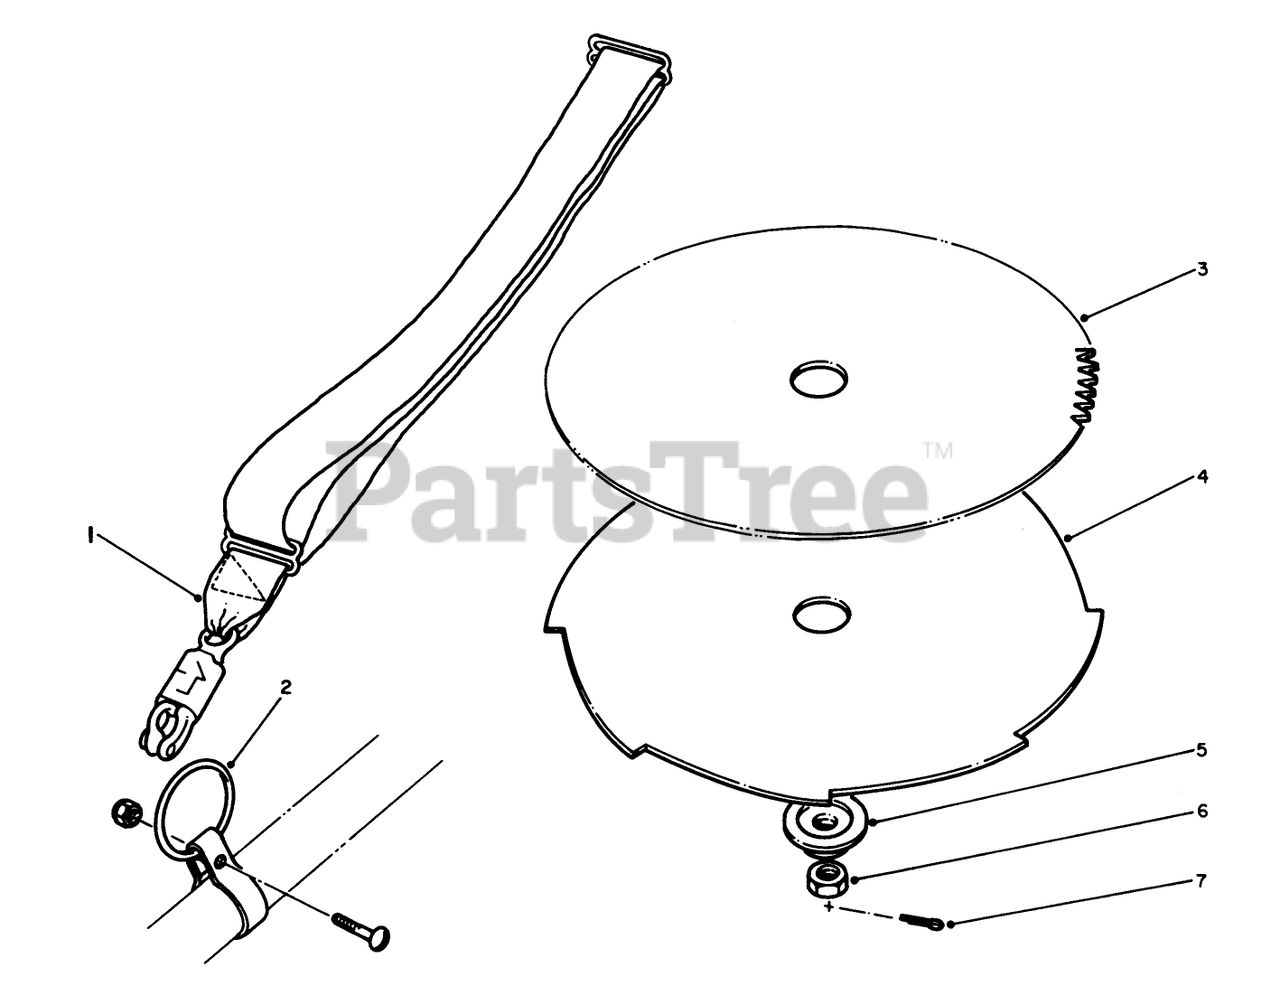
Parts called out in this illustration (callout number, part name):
2	HARNESS CLAMP/RING KIT
3	SAW BLD PKG(8", 80T)
5	Blade Adapter
7	1/16 X 1 LG COTTER PIN
